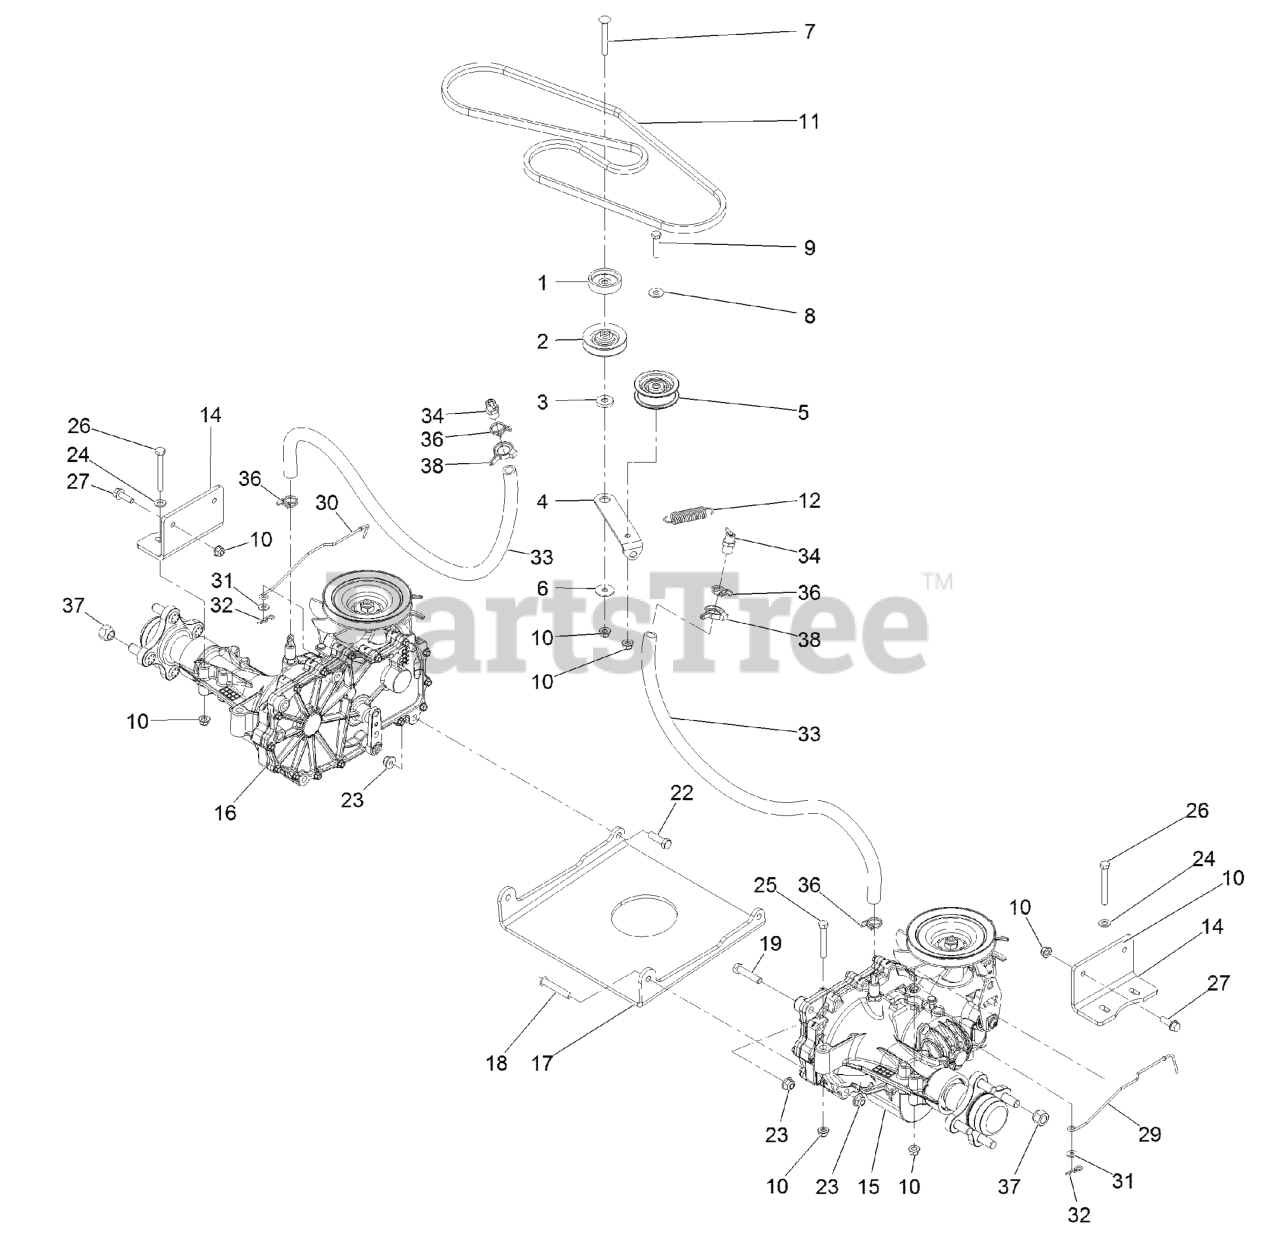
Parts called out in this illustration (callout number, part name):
2	PULLEY-IDLER
3	SPACER-ARM, IDLER
4	Arm-Idler
5	Pulley-Idler, Flat
6	WASHER-PIVOT
7	SCREW-CARR
8	WASHER-FLAT
9	SCREW-HH
10	NUT-HF, NI
12	Spring-Return, Pedal
14	MOUNT-HYDRO
15	LH HYDRO TRANSMISSION ASM
16	RH HYDRO TRANSMISSION ASM
17	PLATE-CROSS, HYDRO
18	SCREW-HH
19	SCREW-HH
22	SCREW-HH
23	NUT-HF, NI
24	WASHER-PLAIN
25	SCREW-HH
26	SCREW-HH
27	SCREW-HHF
29	ROD-BYPASS, LH
30	ROD-BYPASS, RH
33	HOSE-HYDRO
34	BREATHER KIT
36	CLAMP-HOSE
37	NUT-LUG
38	CLAMP-HOSE
